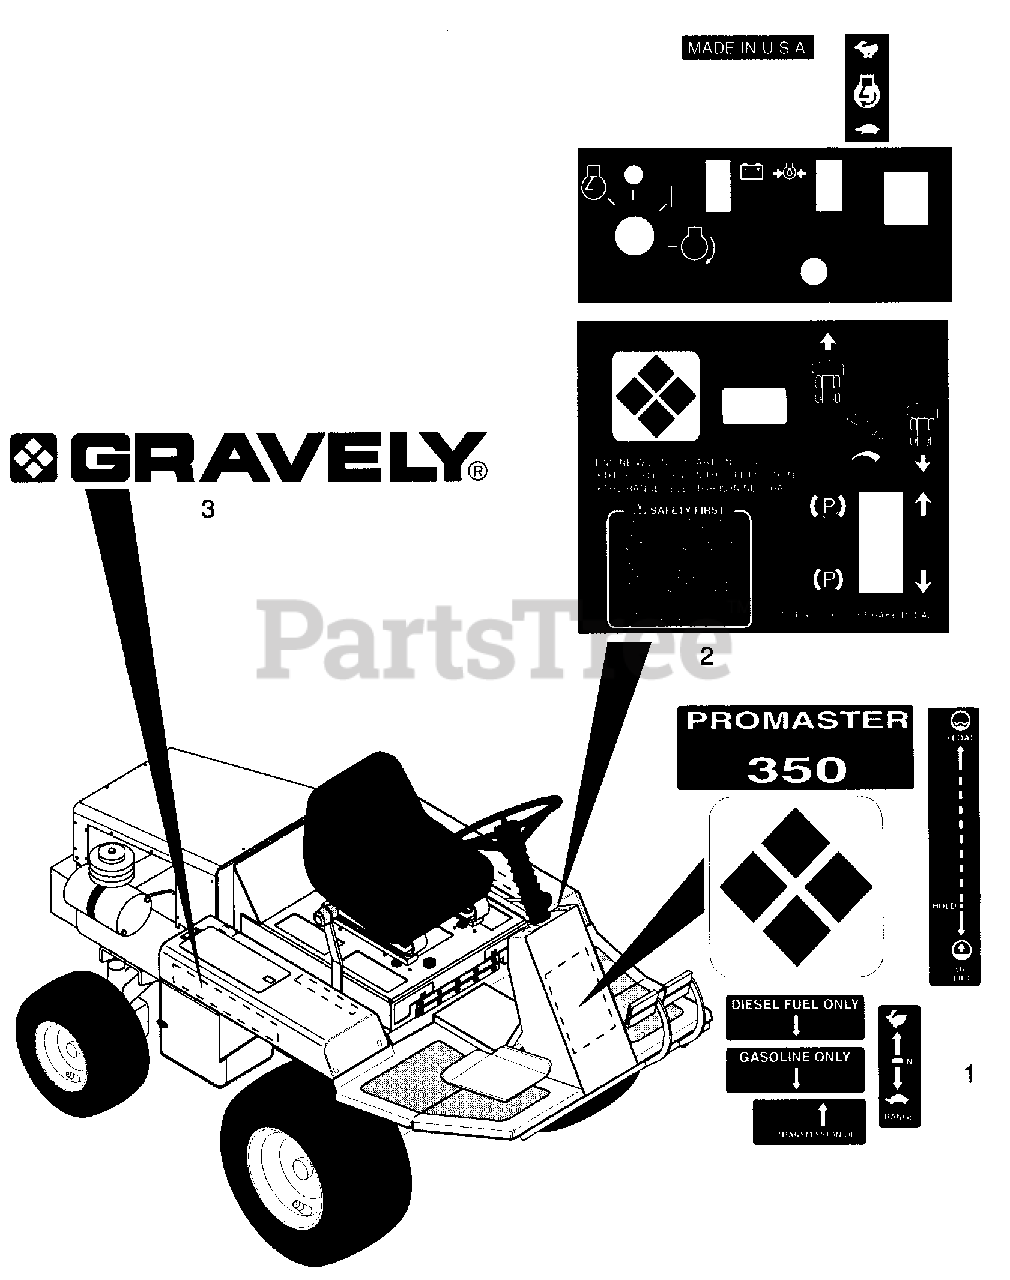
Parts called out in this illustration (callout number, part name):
1	Decal Set
2	Decal Set
3	Decal - Gravely Logo
